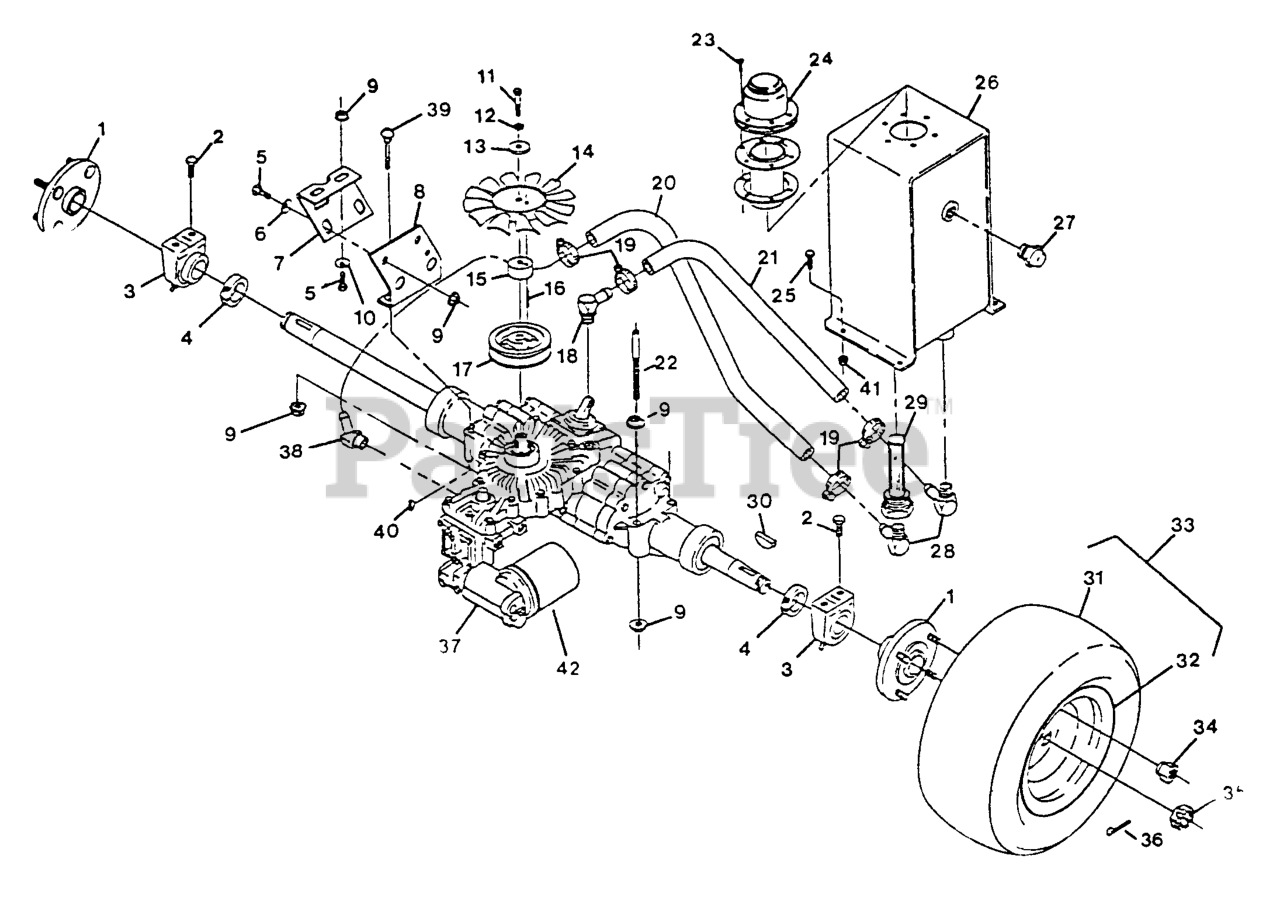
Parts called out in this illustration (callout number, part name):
2	SCREW-HHF
3	BEARING,PILLOW BLOCK
5	SCREW-HH
6	WASHER-BELLEVILLE
8	STABILIZER,AXLE LOWER
9	NUT-HHF, WHIZ
10	WASHER-FLAT
11	SCREW-HH
12	WASHER-LOCK
13	WASHER-RETAINER, PULLEY
14	FAN,7"OD/10BLADE
15	SPACER,FAN
19	CLAMP-HOSE
20	HOSE,HYDRAULIC 16.5
21	HOSE,HYDRAULIC 8.0
22	PIN,GUIDE
24	BREATHER,FILLR & CAP
25	SCREW-HH
27	OIL EYE,HYDRAULIC TANK
29	STRAINER,SUCTION
30	KEY-WOODRUFF
33	WHEEL AND TIRE ASM
34	NUT-LUG
35	NUT-HEX, SLOTTED
36	PIN-COTTER
38	ELBOW-45DEGOR/HSEBRB
39	BOLT,CARRSSN
40	KEY-WOODRUFF
